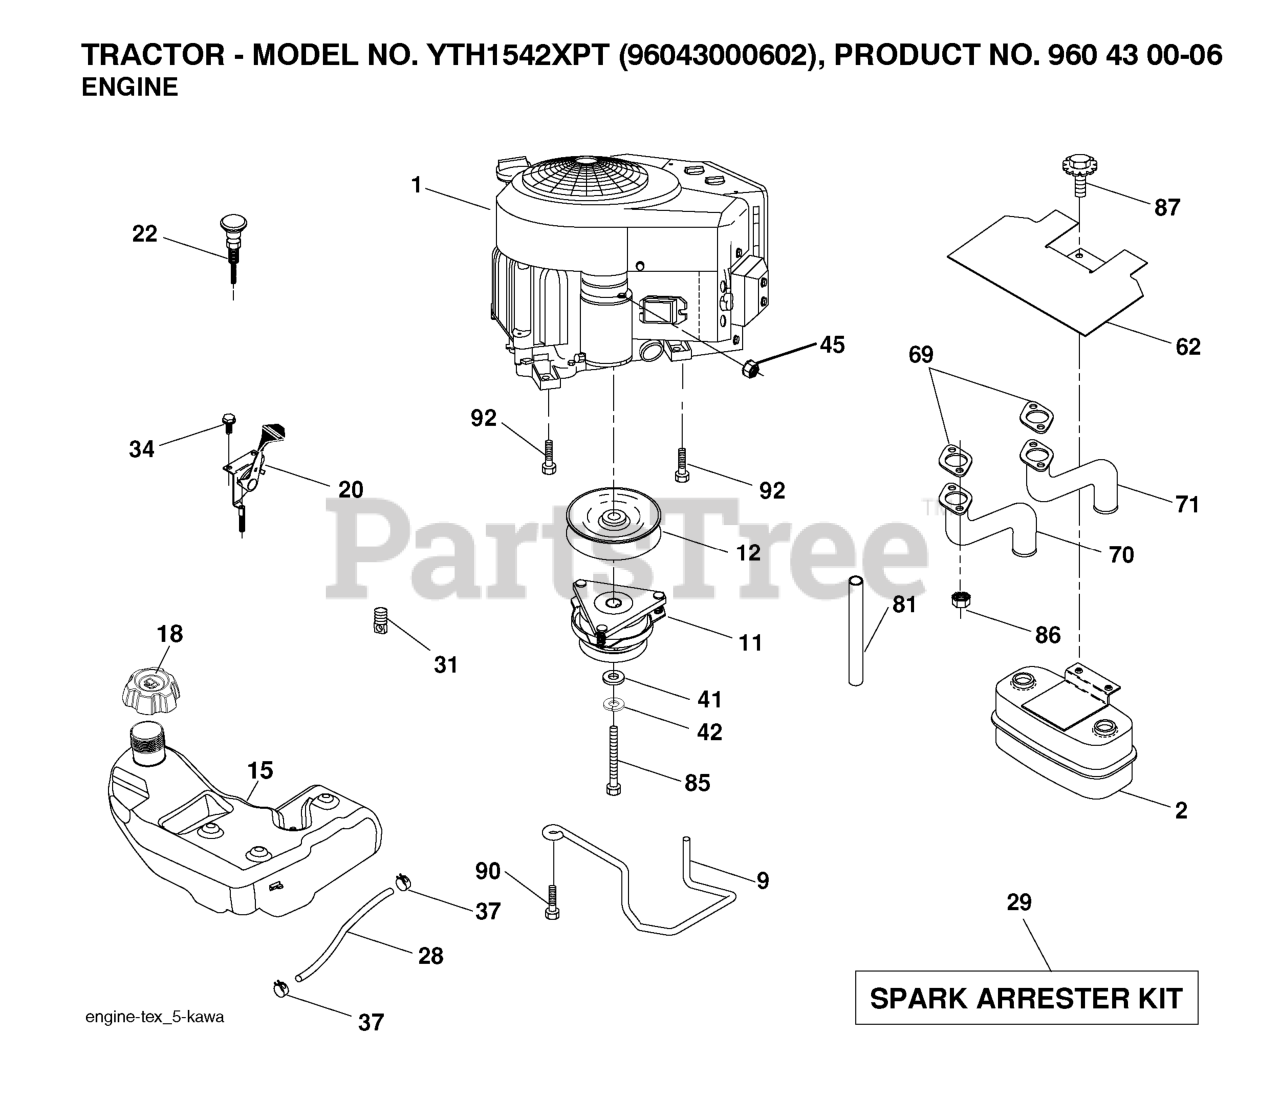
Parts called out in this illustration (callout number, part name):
2	MUFFLER.TWIN.CYL.LOW.TONE
9	KEEPER.BELT.ENGINE.4.2
11	RB.CLUTCH.OGURA.4.4.PD
12	PULLEY.ENGINE.TUFFTORQ
15	TANK.FUEL.4GAL
18	CAP.FUEL.TANK.3"GREY
20	THROTTLE CONTROL
21	SCREW
22	CONTROL, CHOKE
28	LINE.FUEL.64"REAR.EMIS
29	KIT.SPARK ARRESTOR 794945 B&S
37	HOSE CLAMP
42	LOCKWASHER
45	NUT
62	RP SHIELD HEAT MUFFLER
69	GASKET.MUFFLER
70	EXHAUST TUBE LH KAWI
71	EXHAUST TUBE RH KAWI
81	TUBE, DRAIN OIL ASM.
85	BOLT HEX 7/16-20X4-1/4"
86	NUT.HEX.FLANGE.TOPLOCK
87	BOLT.5/16-18UNCX1.W/SEMS.BLK
90	SCREW 3/8-16X1
92	SCREW 3/8-16X1
